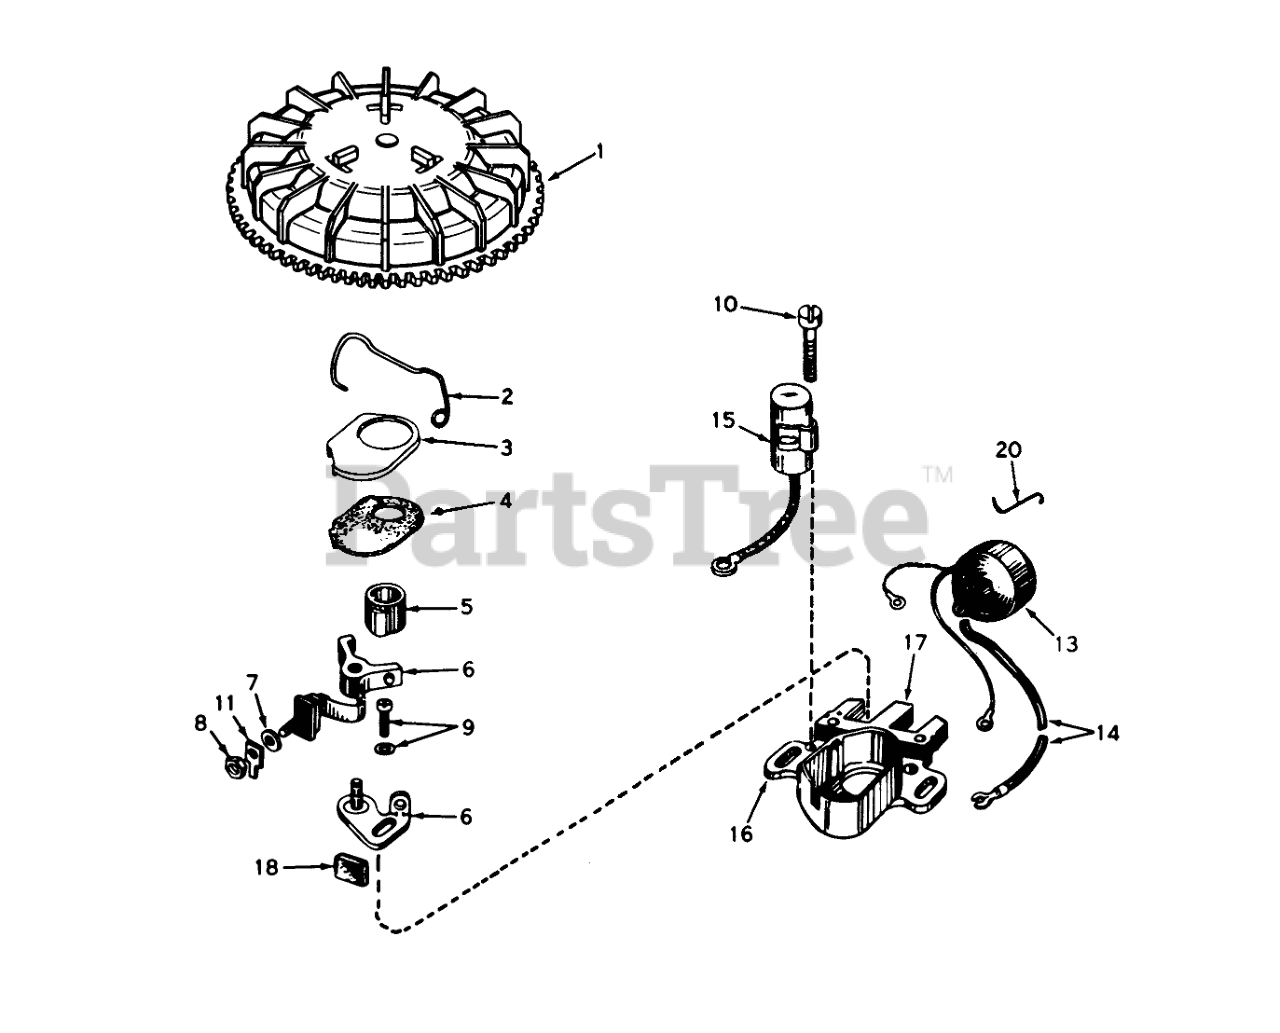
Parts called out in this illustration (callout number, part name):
1	Flywheel (Incl. Ref. #3 & 4)
2	Spring Breaker Box
3	Cover-Dust
4	Gasket, Dust Cover
5	Cam-Breaker
6	Breaker Assy.
7	Washer
8	DECAL
9	Breaker Screw
10	Condenser Screw
11	Terminal, Ground
13	Coil Assy. (Incl. Ref. #14)
14	Wire, Lead
15	Condenser
16	Core & Plate
17	Stator Assy. (Incl. Ref. #2, 3, 4, 6 thru 16, 18 & 20)
18	Felt,Cam Wiper
20	Clip, Coil
